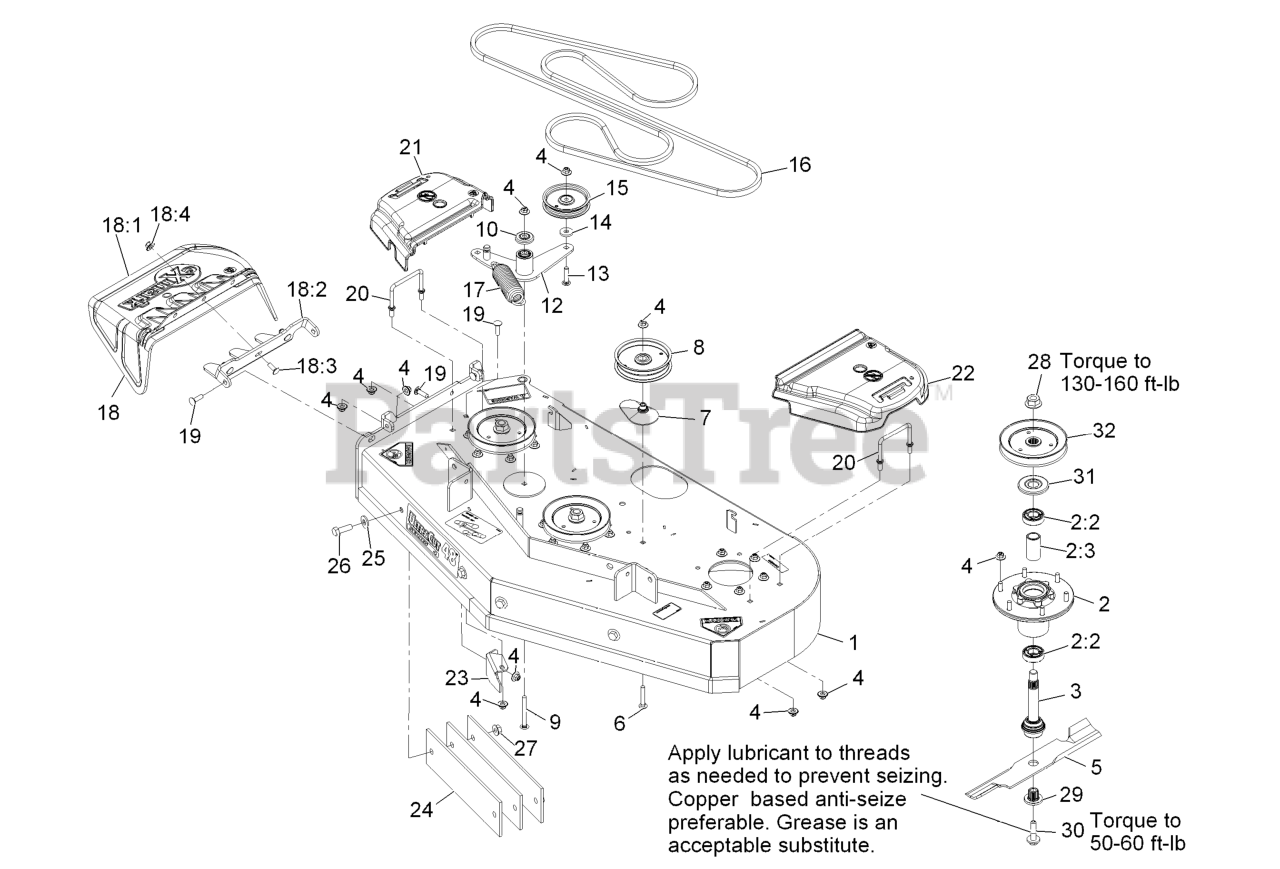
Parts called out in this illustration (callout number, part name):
1	DECK ASM-484
2	ASM-CUTTER HSG WITH BEARINGS
2:2	BEARING-BALL
2:3	SPACER-BEARING
3	ASM-SPINDLE AND SEAL
4	Nut-Nyloc 3/8-16 Flg
6	Bolt-Carriage 3/8-16 X 2 1/4
7	SPACER-PULLEY
8	PULLEY-IDLER
9	SCREW-CARR
10	GUARD-TOP
12	IDLER ARM ASM W/BEARINGS
13	SCREW-CARR SPECIAL
15	PULLEY-IDLER
16	V-BELT
18	ASM,DISCHARGE CHUTE
18:1	CHUTE,DISCHARGE
18:2	BRACKET,DISCHARGE CHUTE
18:3	SCREW-CARR
18:4	Nut-Nyloc 3/8-16 Flg
19	Bolt-Carriage 3/8-16 X 1 1/4
20	WIREFORM-COVER
21	COVER-BELT, RH
22	COVER-BELT, LH
23	BAFFLE,DISCHARGE
24	BAR,WEIGHT
25	WASHER-SPRING
26	SCREW-HH
27	NUT-HHF
28	NUT-FLANGE
29	BUSHING,SPLINED
30	SCREW,SEMS 1/2-20 X 2.19
31	GUARD,BEARING TOP .989
32	SHEAVE,BLADE DRIVE 5.90
